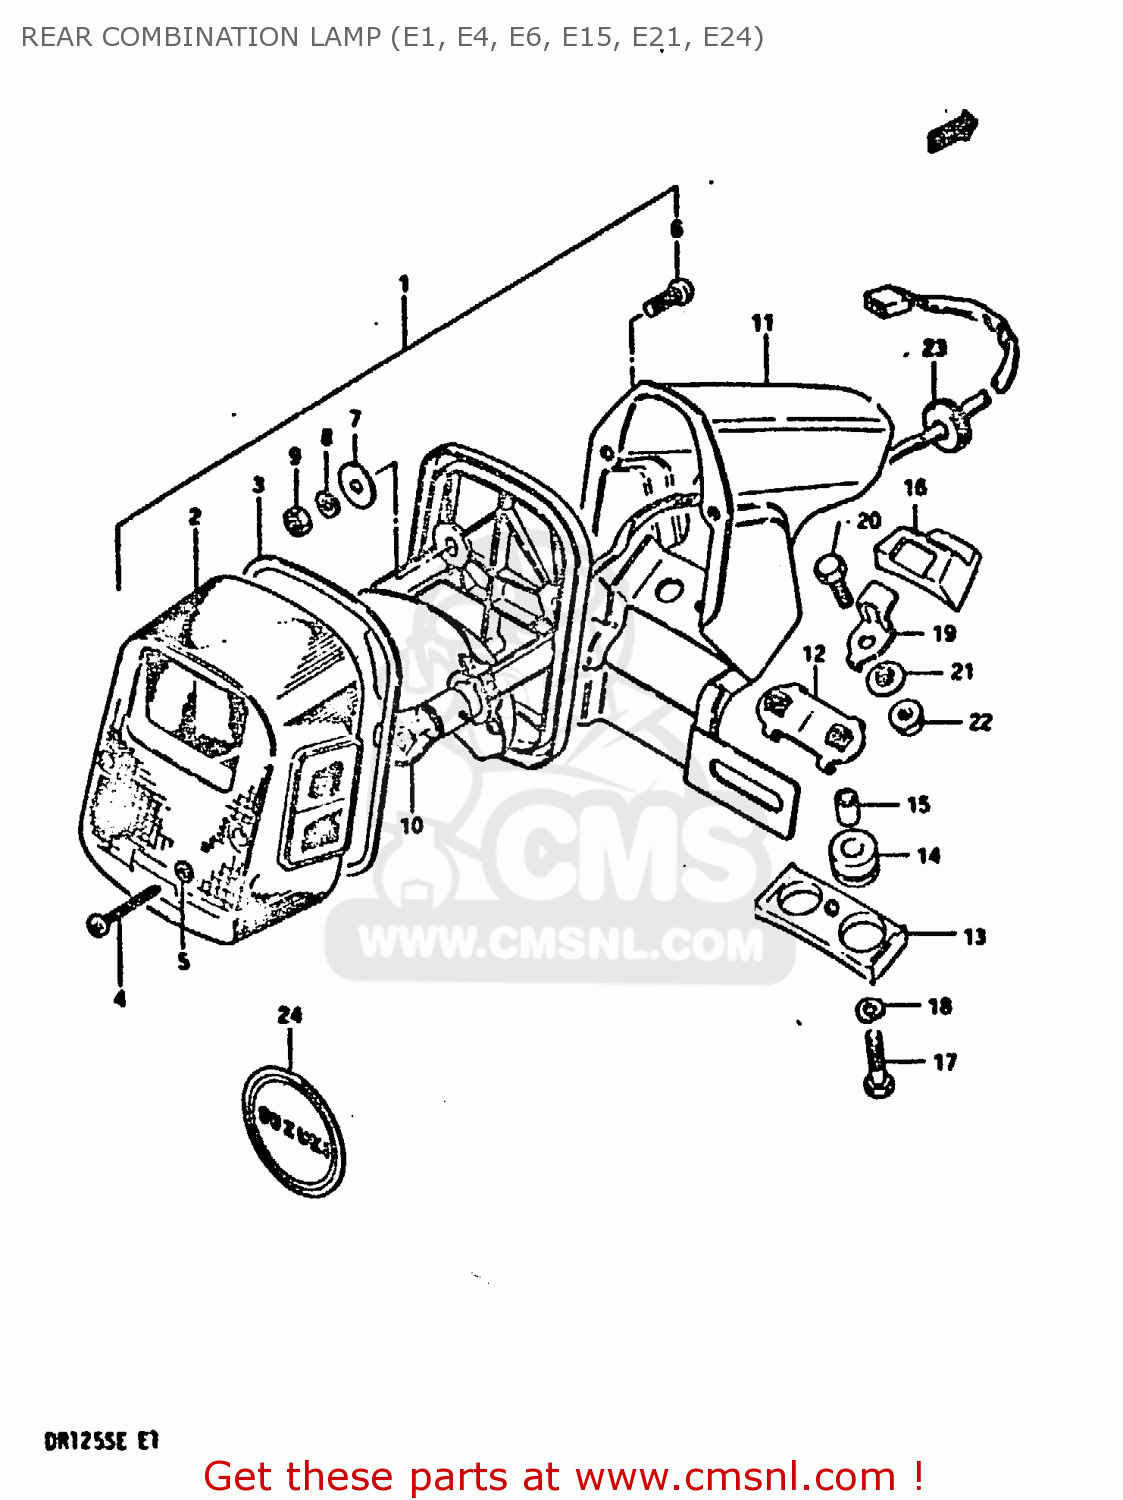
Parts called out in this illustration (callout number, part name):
1	LAMP UNIT,RR COMBNATION
2	LENS
3	GASKET (NAS)
4	SCREW TAPP.
5	GASKET (NAS)
6	SCREW
7	WASHER,REAR COMBINATION LAMP
8	LOCK WASHER
9	NUT
10	BULB 12V21/5W
11	BRACKET UNIT,TAIL LAMP
12	PLATE
13	CUSHION
14	CUSHION
15	SPACER
16	CUSHION,REAR COMBINATION LAMP
17	BOLT
18	WASHER,LOCK
19	PLATE,RR COMBINATION LAMP
20	BOLT
21	WASHER,LOCK
22	NUT
23	GROMMET
24	EMBLEM, REAR
